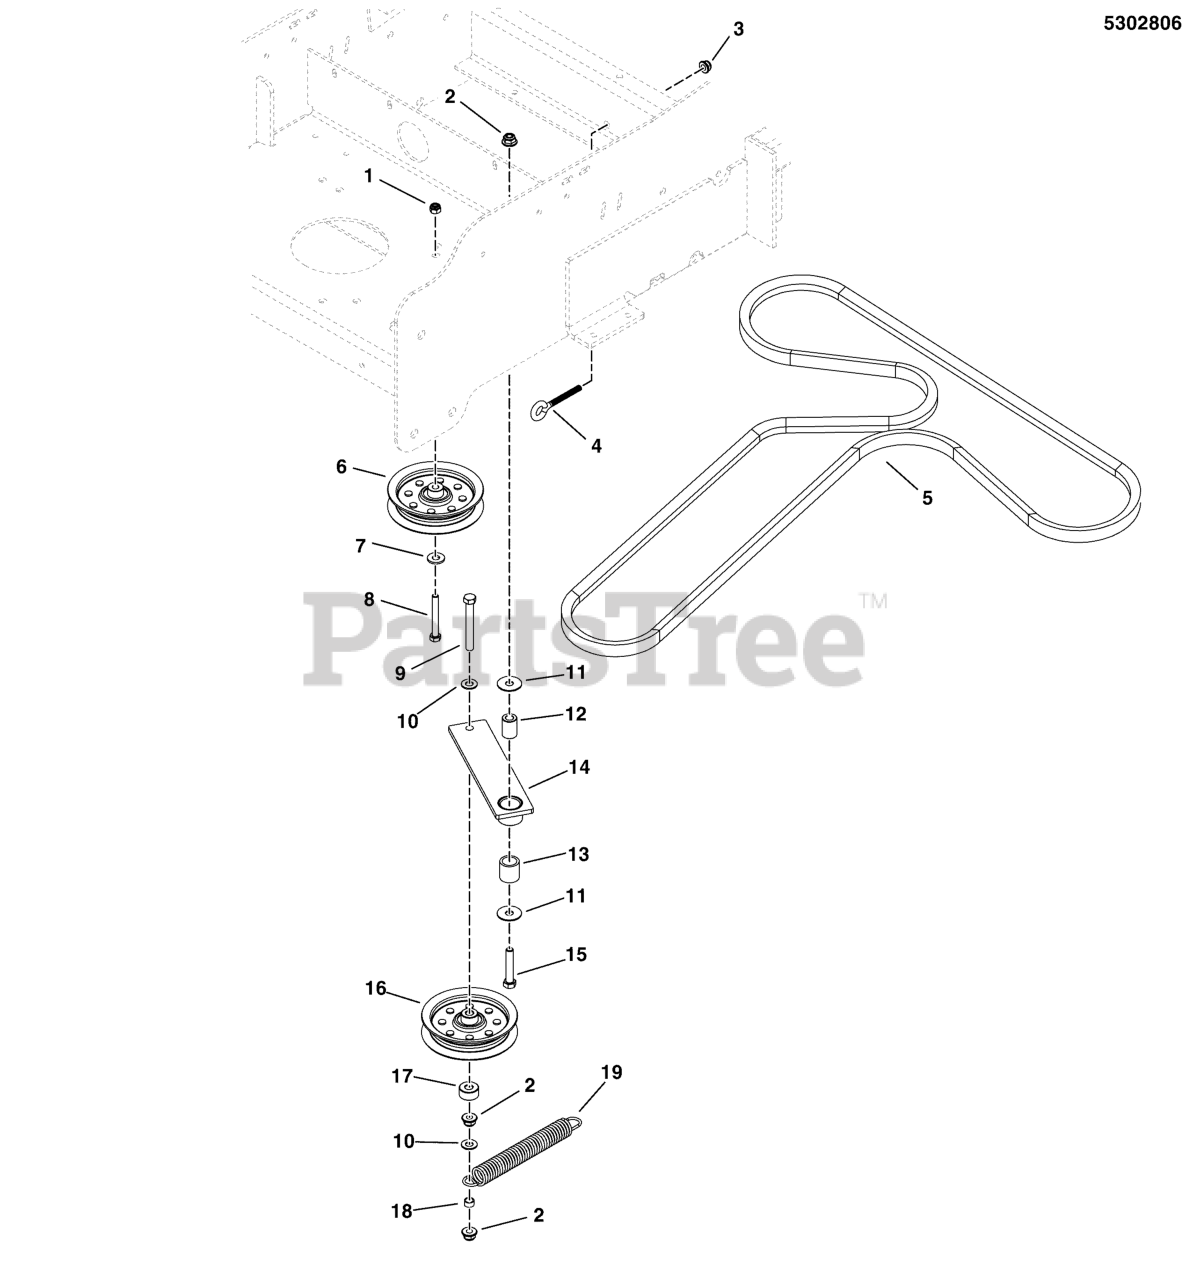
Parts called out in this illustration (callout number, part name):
1	NUT, Hex, Nylon Locking, 5/16-18
2	NUT, 3/8 - 16 HEX NYLOCK FLANGE
3	NUT, 5/16-18 HEX NYLOCK FLANGE NUT
4	EYE BOLT,5/16-18 X3.5,2.13THRD,.55EYE,CZ
5	BELT, SPA-SEC, 66.26" EL, ARAMID, WRAPED
6	PULLEY-IDLER, 4.06OD, .315ID, .75W STL
7	WASHER, 5/16" USS
8	BOLT, 5/16-18 X 2-1/2" GD5 YZ
9	BOLT, 3/8-16 X 3 GD5 TFL
10	WASHER, 3/8 SAE
11	WASHER, 3/8" Fender
12	SPACER, .38 X .75 X 1.06, YZ
13	BUSHING, BRASS, 3/4 X 1 X 1
15	BOLT, 3/8-16 X 2, GD5, CZ
16	PULLEY-IDLER, 4.06OD, .375ID, .75W STL
17	SPACER, .39 X 1.00 X .50, PM, CZ
18	SPACER, .38 X .50 X .27, CZ
19	SPRING, EXTENSION, 1.00
